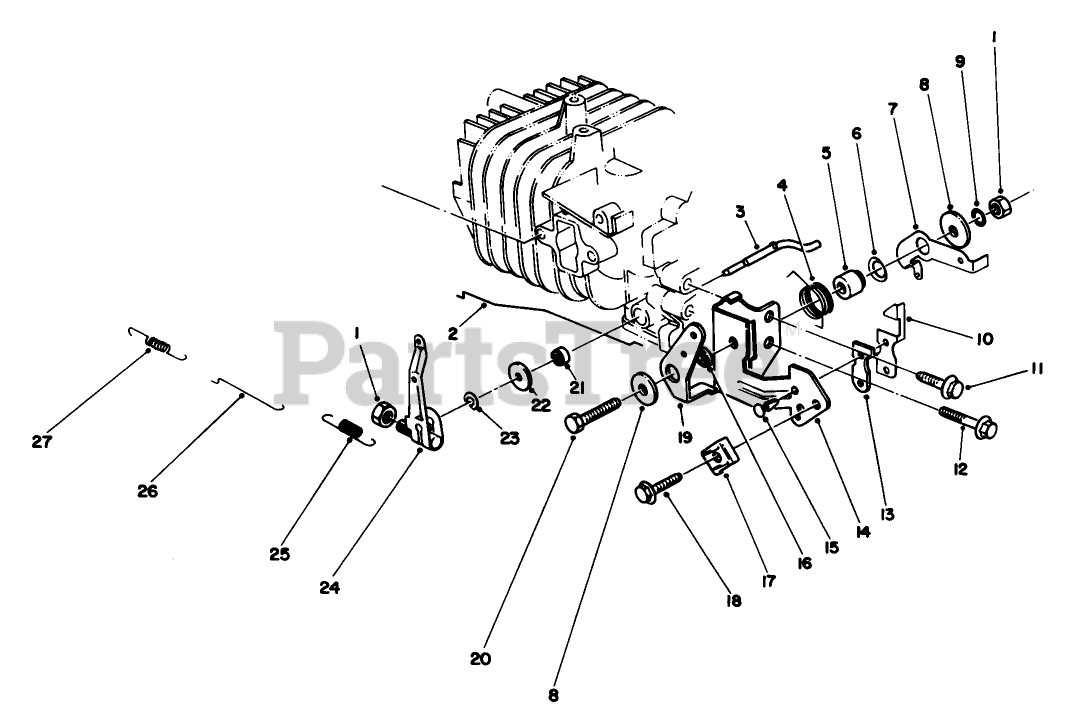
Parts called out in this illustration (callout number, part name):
2	CHOKE ROD
3	Shaft-Govemor
4	SPRING-CHOKE LEVER
5	Gov Lever Spacer
6	Washer-Gov. Spring Lever
7	LEVER-SPRING, GOVERNOR
8	WASHER
9	LOCKWASHER
10	TERMINAL-KILL SWITCH
13	INSULATOR-KILL SWITCH
14	BRACKET-THROTTLE, CONTROL
15	KILL SWITCH RIVET
16	SPACER-CHOKE LEVER
17	CLAMP
19	LEVER-CONTROL, CHOKE
21	SEAL-OIL
22	WASHER
23	E-RING
24	GOVERNOR ARM
25	SPRING-GOVERNOR
26	ROD-CARBURETOR
27	SPRING
